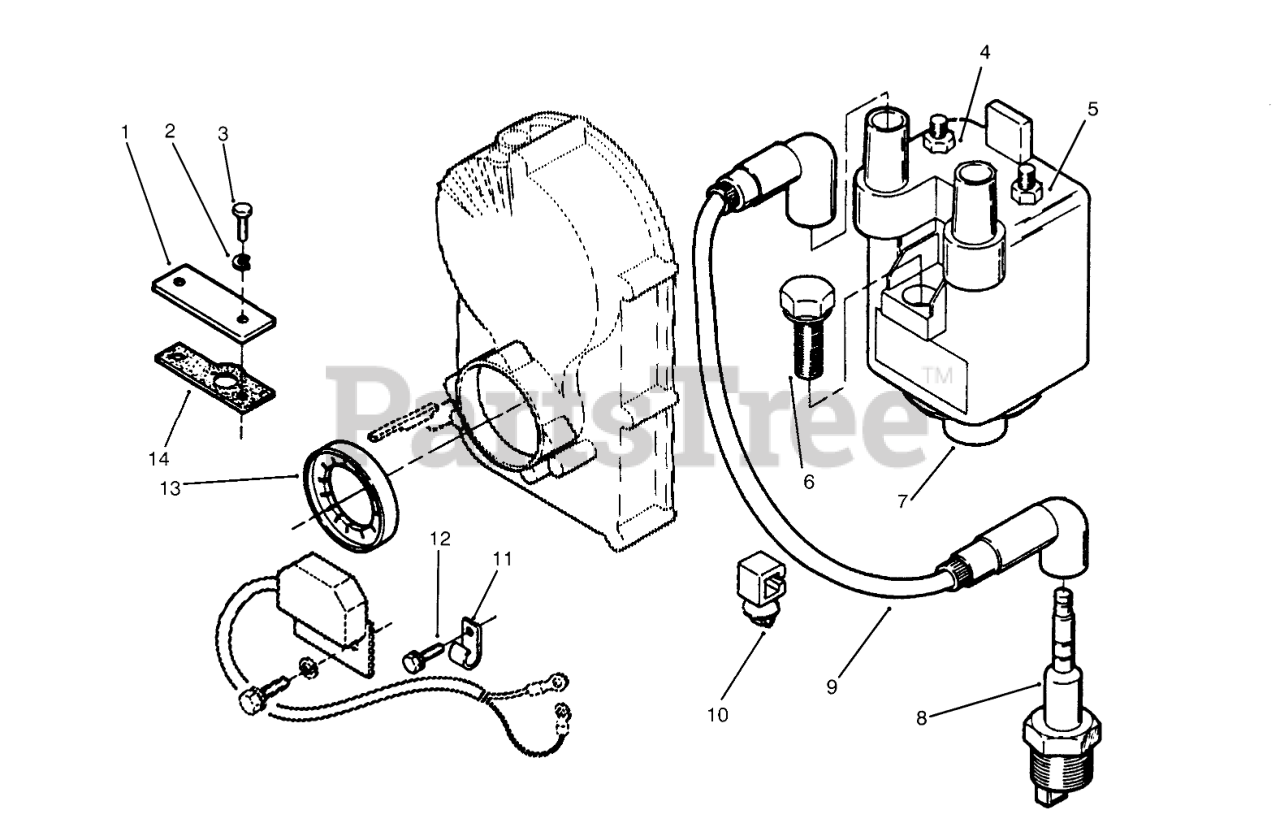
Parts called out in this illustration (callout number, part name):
1	PLATE-COVER
2	WASHER-FLAT
3	SCREW - CAP HEX HEAD
4	NUT-HEX FLANGE
5	NUT-HEX FLANGE
6	HEX-HEAD CAP SCREW
7	Coil-Battery Ignition (Incl. Ref. #4-5)
8	SPARK PLUG
9	Wire-Plug
10	WIRE ROUTING CLIP
11	CLIP-WIRE
12	SCREW-HH
13	ROTOR-IGNITION
14	Gasket-Plate
